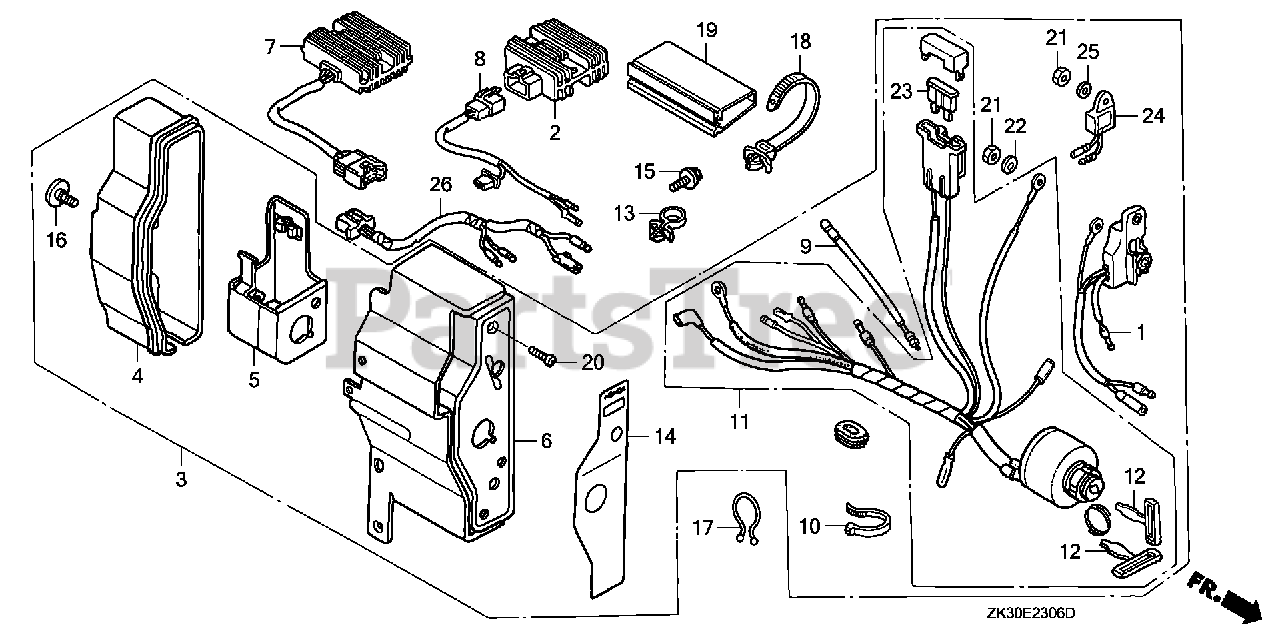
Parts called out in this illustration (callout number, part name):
3	BOX ASSY., CONTROL (18A) *NH1* (EXP-ALERT) (BLACK)
3	BOX ASSY., CONTROL (18A) *R280* (EXP-ALERT) (POWER RED)
4	CASE, CONTROL
5	BRACKET, CASE MOUNTING
6	PANEL, CONTROL *NH1* (BLACK)
6	PANEL, CONTROL *R8* (BRIGHT RED)
6	PANEL, CONTROL *R280* (POWER RED)
7	RECTIFIER ASSY., REGULATOR (20A)
9	SUB-WIRE HARNESS
11	SWITCH ASSY., COMBINATION (18A-CHARGE)
12	KEY (HONDALOCK)
13	HOLDER, STOP SWITCH WIRE
14	MARK, CONTROL BOX (EXTERNAL-REGULATOR)
15	BOLT, FLANGE (6X12) (CT200)
16	SCREW, SPECIAL (6X12)
17	CLIP, PURSE LOCK
18	STRAP, CABLE (118MM) (BLACK)
19	TUBE, FASTENER (30MM)
20	SCREW, PAN (4X12)
21	NUT, HEX. (4MM)
22	WASHER, SPRING (4MM)
23	FUSE, BLADE (25A)
24	ALERT UNIT, OIL
25	WASHER, PLAIN (4MM)
26	SUB-WIRE HARNESS ASSY.
